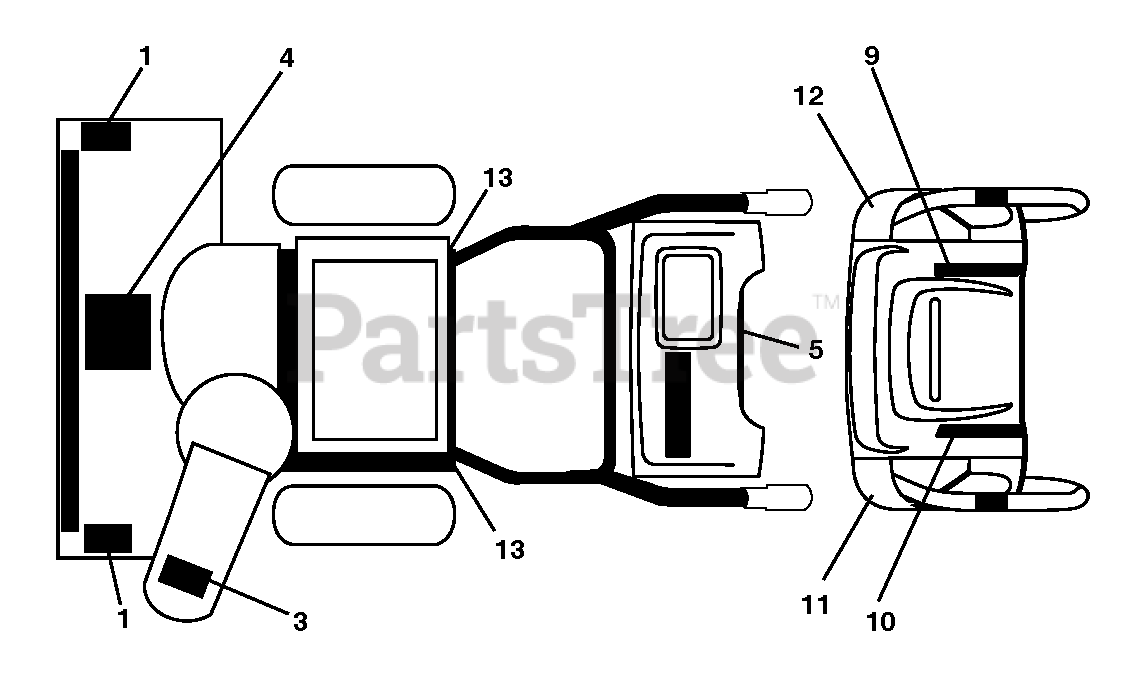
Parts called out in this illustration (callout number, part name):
1	DECAL.AUGER.SAFETY.
3	DECAL.CHUTE.SAFETY.
4	DECAL.AUGER."
5	DECAL.NOISE.LEVEL.105DB/CE.EAC
9	DECAL CONSOLE DECAL DECAL.SNOW
10	DECAL CONSOLE DECAL DECAL.SNOW
11	DECAL,HEIGHTADJUST
12	DECAL.CONSOLE.HAND.WARMER
13	DECAL.BELT.GUARD.
